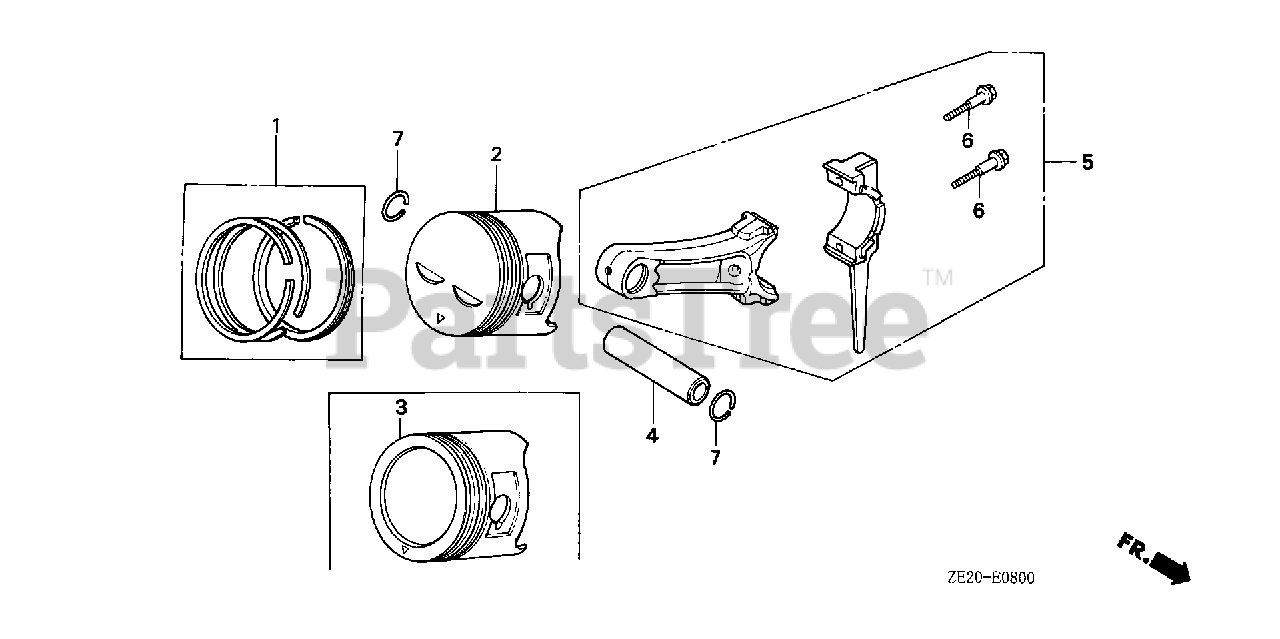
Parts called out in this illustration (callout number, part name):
1	RING SET, PISTON (STD) (NIPPON)
1	RING SET, PISTON (STD) (TEIKOKU)
1	RING SET, PISTON (0.25) (NIPPON)
1	RING SET, PISTON (0.25) (TEIKOKU)
1	RING SET, PISTON (0.50) (NIPPON)
1	RING SET, PISTON (0.50) (TEIKOKU)
1	RING SET, PISTON (0.75) (NIPPON)
1	RING SET, PISTON (0.75) (TEIKOKU)
2	PISTON (STD)
2	PISTON (0.25)
2	PISTON (0.50)
2	PISTON (0.75)
2	PISTON (0.75) (NOT AVAILABLE)
4	PIN, PISTON
5	ROD ASSY., CONNECTING (STD)
5	ROD ASSY., CONNECTING (0.25 LOWER SIZE)
6	BOLT, CONNECTING ROD
7	CLIP, PISTON PIN (18MM)
